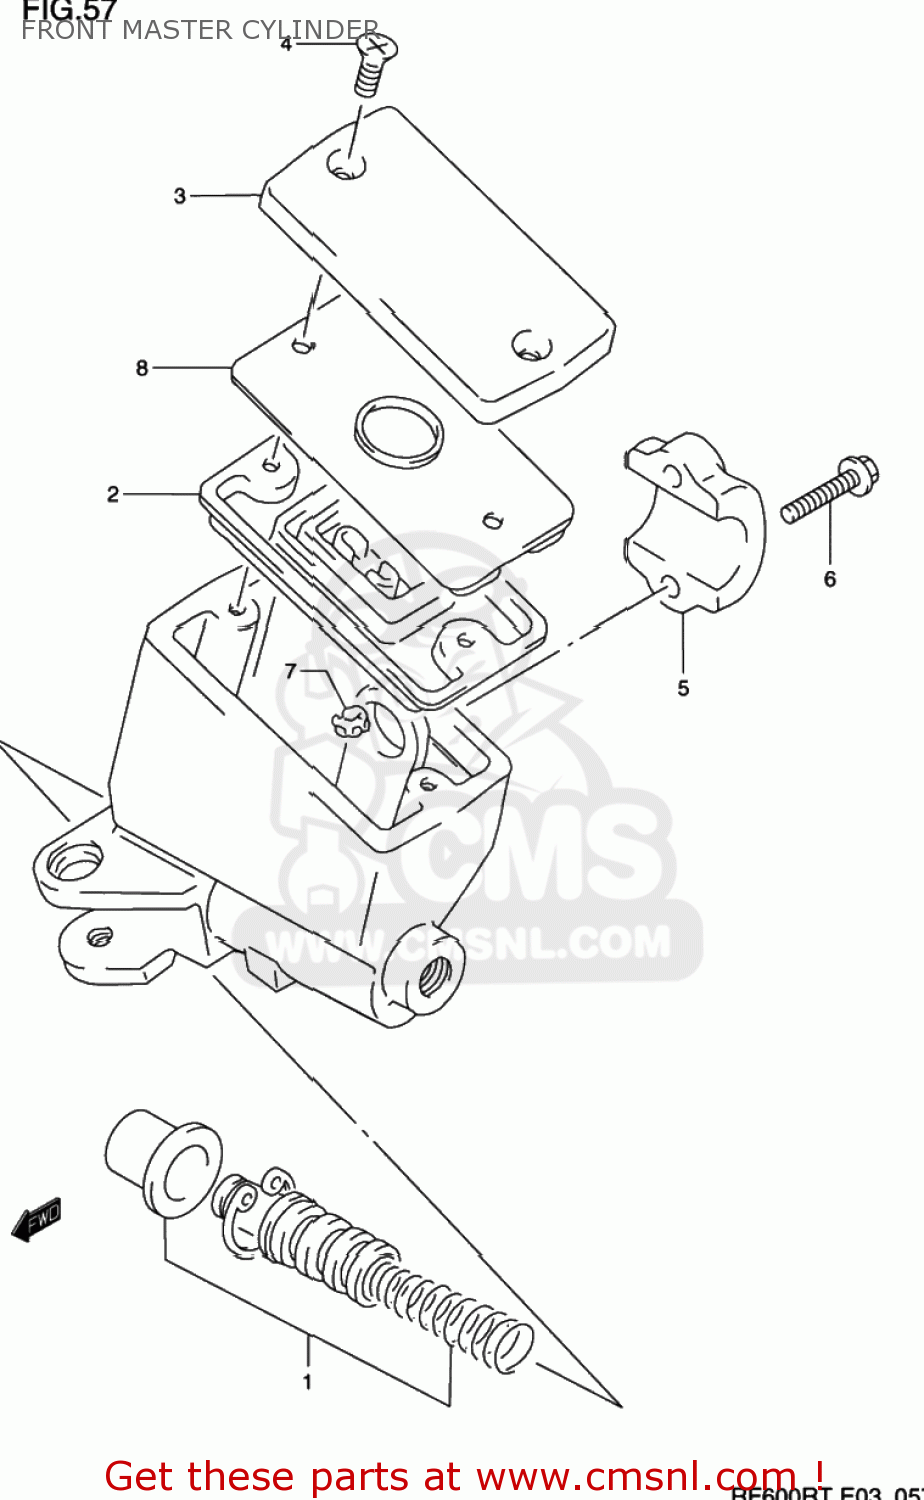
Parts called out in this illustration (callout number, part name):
1	PISTON/CUP SET
2	3
3	CAP
4	SCREW
5	HOLDER
6	BOLT(6X25)
7	PROTECTOR
8	PLATE,DIAPHRAGM
